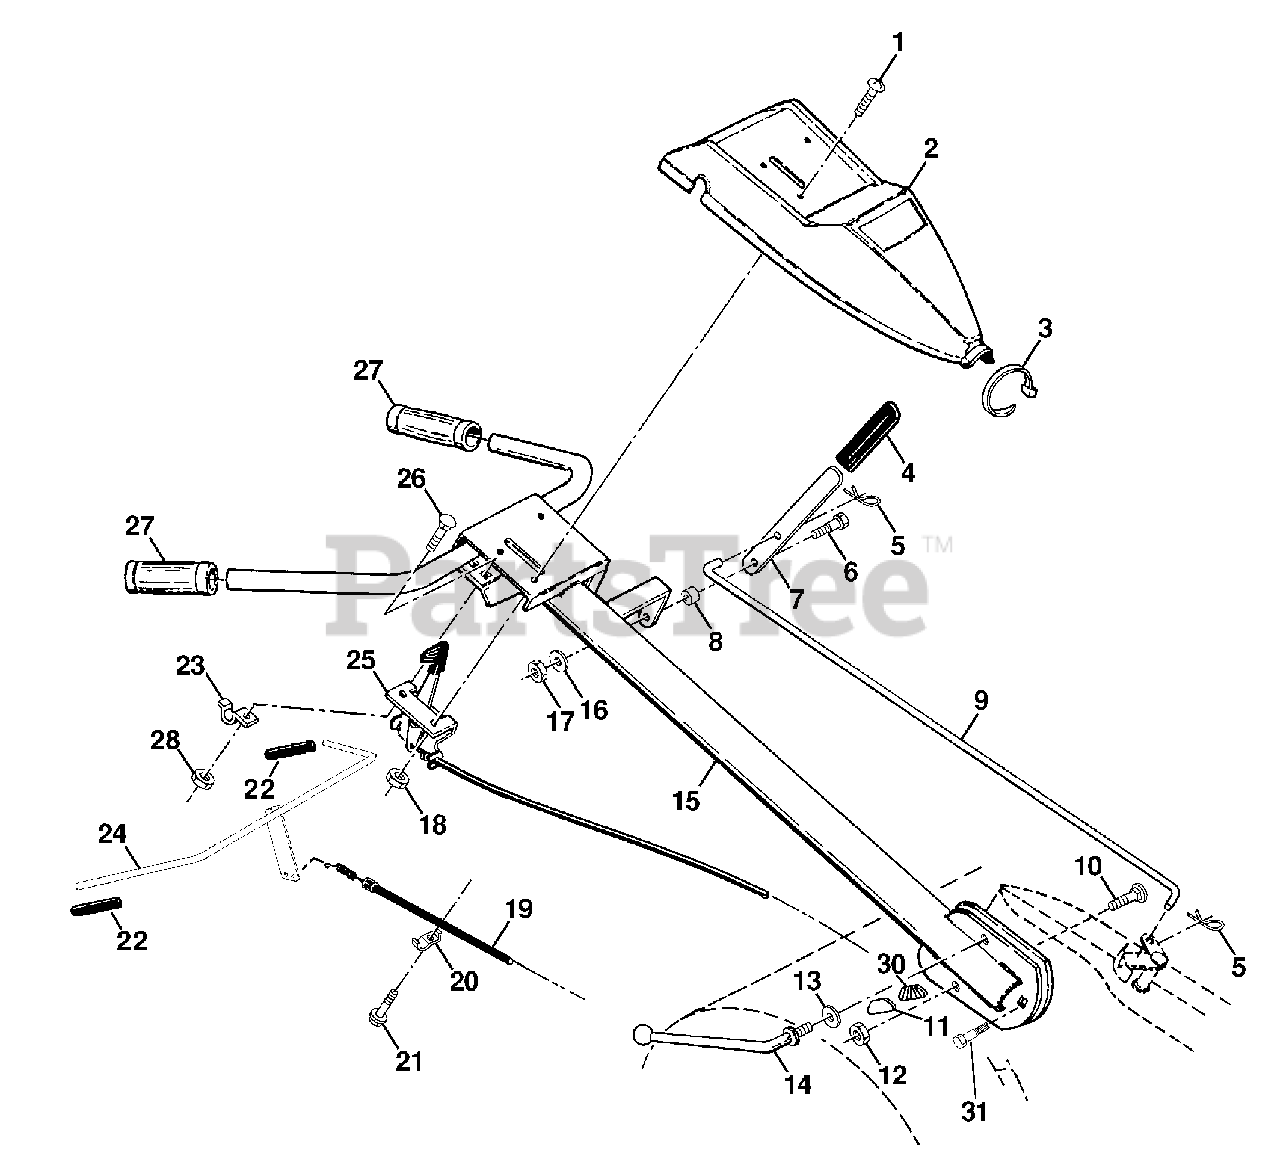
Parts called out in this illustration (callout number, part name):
1	Screw, Pan Hd. #10-24 UNC
2	Panel, Control
3	Tie, Cable
4	Grip, Handle
5	Clip, Hairpin
6	Bolt, Shoulder
7	Handle, Shift
8	Grommet, Rubber
9	Rod, Shift
10	Bolt, Carriage 3/8-16 x 1
11	Lock, Handle
12	Nut, Centerlock 3/8-16
13	Washer 13/32 x 1 x 11 Ga.
14	Lever, Lock, Handle
15	Handle
16	Washer, Lock 1/4
17	Nut, Hex 1/4-20
18	Nut, Keps #10-24 UNC
19	Cable, Clutch
21	Screw, Hex Washer Hd. Slotted #10-24 x 1/2
22	Grip, Bar, Control
23	Clamp, Bar, Control
24	Bar Assembly, Control
25	Control, Throttle
26	Bolt, Carriage 1/4-20 UNC x 1/2
27	Grip, Handle
28	Nut, Keps Hex 1/4-20
30	Lock, Handle
31	Bolt, Pivot
